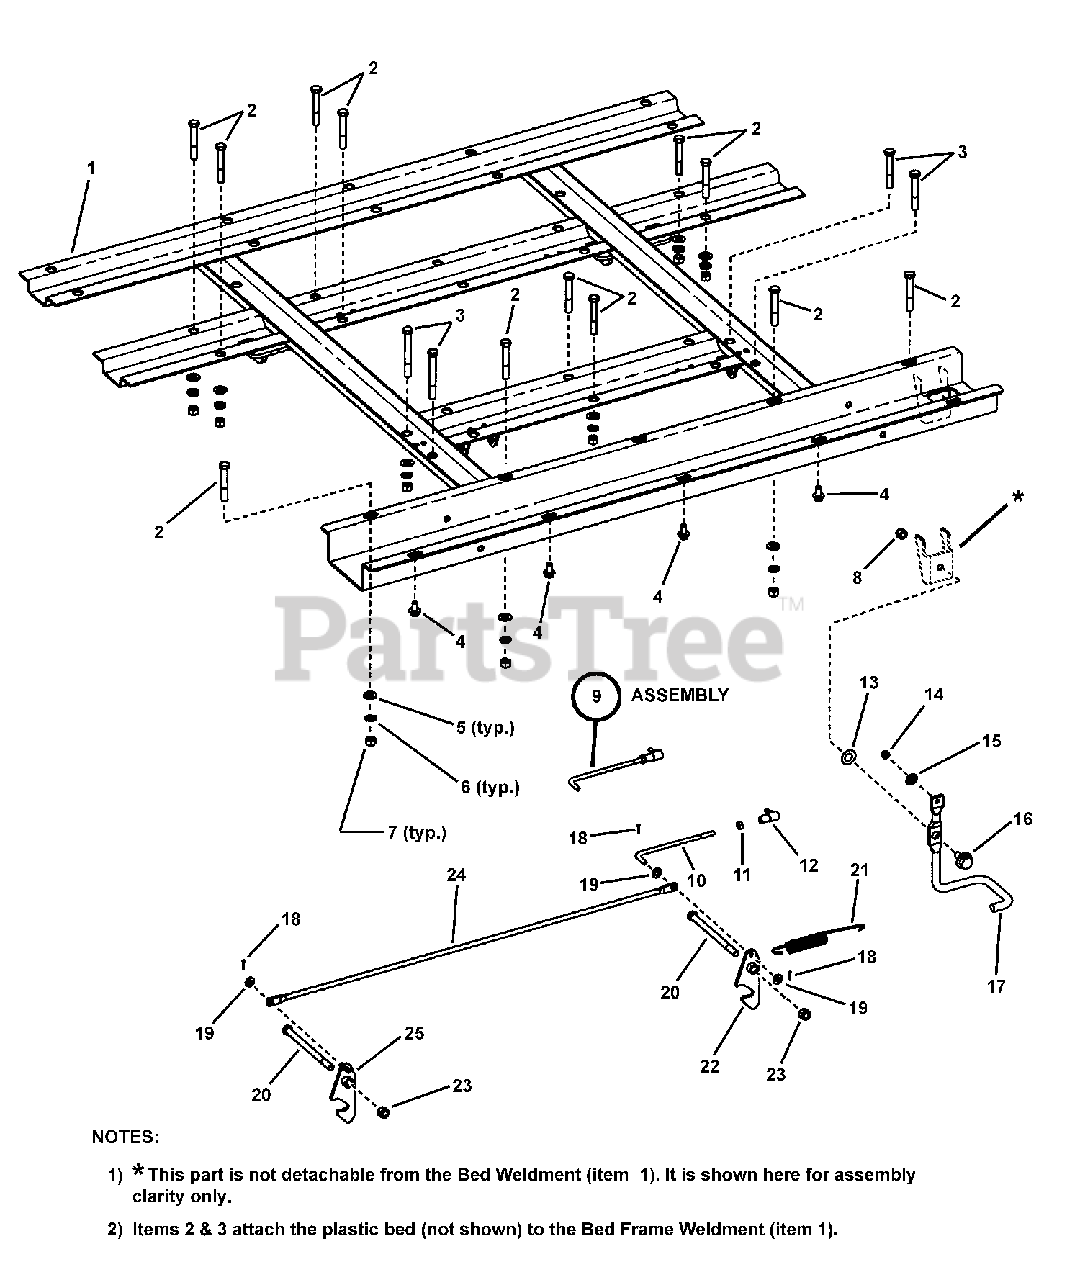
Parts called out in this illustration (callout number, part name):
1	WELDMENT, Bed Frame
2	SCREW, 3/8-16 x 2-1/2" Hex Head Cap, GR 5
3	SCREW, 3/8-16 x 3-1/4", Hex Head Cap, GR 5
4	BOLT, 5/16-18 x 5/8" Hex Flange Lock, GR 5
5	WASHER, 3/8" SAE Flat
6	WASHER, 3/8" Split Lock
7	NUT, 3/8-16 Hex, GR 5 or B
8	NUT, 3/8-24 Hex Nyloc
9	ASSEMBLY, Rod-Link (incl. 1 each of items 10, 11 & 12)
10	ROD-LINK (1/4-28 thread)
11	NUT, 1/4-28 Hex, GR 5 or B
12	BALL JOINT, 1/4-28
13	WASHER, .5 x 1.0 x .03 Flat
14	NUT, 1/4-28 Hex, GR 5 or B
15	WASHER, 1/4" Internal Tooth Lock
16	BOLT, 3/8-24 Hex Flange Shoulder, GR 8
17	HANDLE, Bed Latch
18	COTTER PIN, .06 x .50
19	WASHER, .28 x .63 x .06 Flat
20	SCREW, 3/8-16 x 5-1/2" Hex Head Cap, GR 5
21	SPRING, Extension
22	HOOK, Bed (weldment)
23	NUT, 3/8-16 Hex Nyloc
24	ROD, Link
25	HOOK, Bed Ass'y (weldment)
